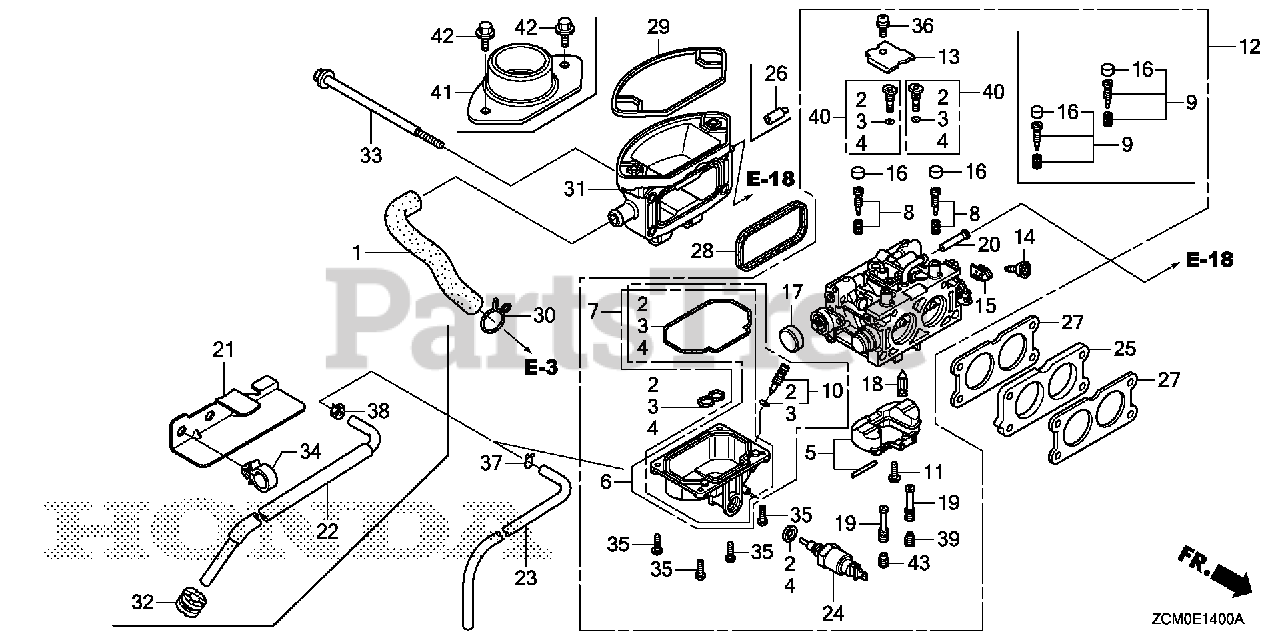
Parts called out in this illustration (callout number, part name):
1	TUBE, BREATHER
2	GASKET SET
6	CHAMBER SET, FLOAT
10	SCREW SET, DRAIN
11	SCREW, FLOAT
12	CARBURETOR ASSY. (BK05A C)
14	SCREW, THROTTLE STOP
15	ARM, THROTTLE LINKAGE
16	CAP, ADJUSTING SCREW (CARBURETOR NO.)
17	CAP, CHOKE DUST
18	VALVE, FLOAT
19	NOZZLE, MAIN
20	SCREEN, FUEL STRAINER
23	TUBE, DRAIN
24	VALVE ASSY., SOLENOID
25	INSULATOR, CARBURETOR
27	GASKET, CARBURETOR
28	GASKET, AIR CLEANER
29	SEAL, AIR CLEANER HOUSING
30	CLIP, BREATHER TUBE
31	ELBOW, AIR CLEANER
33	BOLT, FLANGE (6X106)
35	SCREW, PAN (4X12)
36	SCREW-WASHER (5X10)
37	CLIP, TUBE (B8)
39	JET, MAIN (#105)
39	JET, MAIN (#110)
39	JET, MAIN (#118)
40	JET SET, PILOT (#45)
43	JET, MAIN (#105)
43	JET, MAIN (#110)
43	JET, MAIN (#118)
